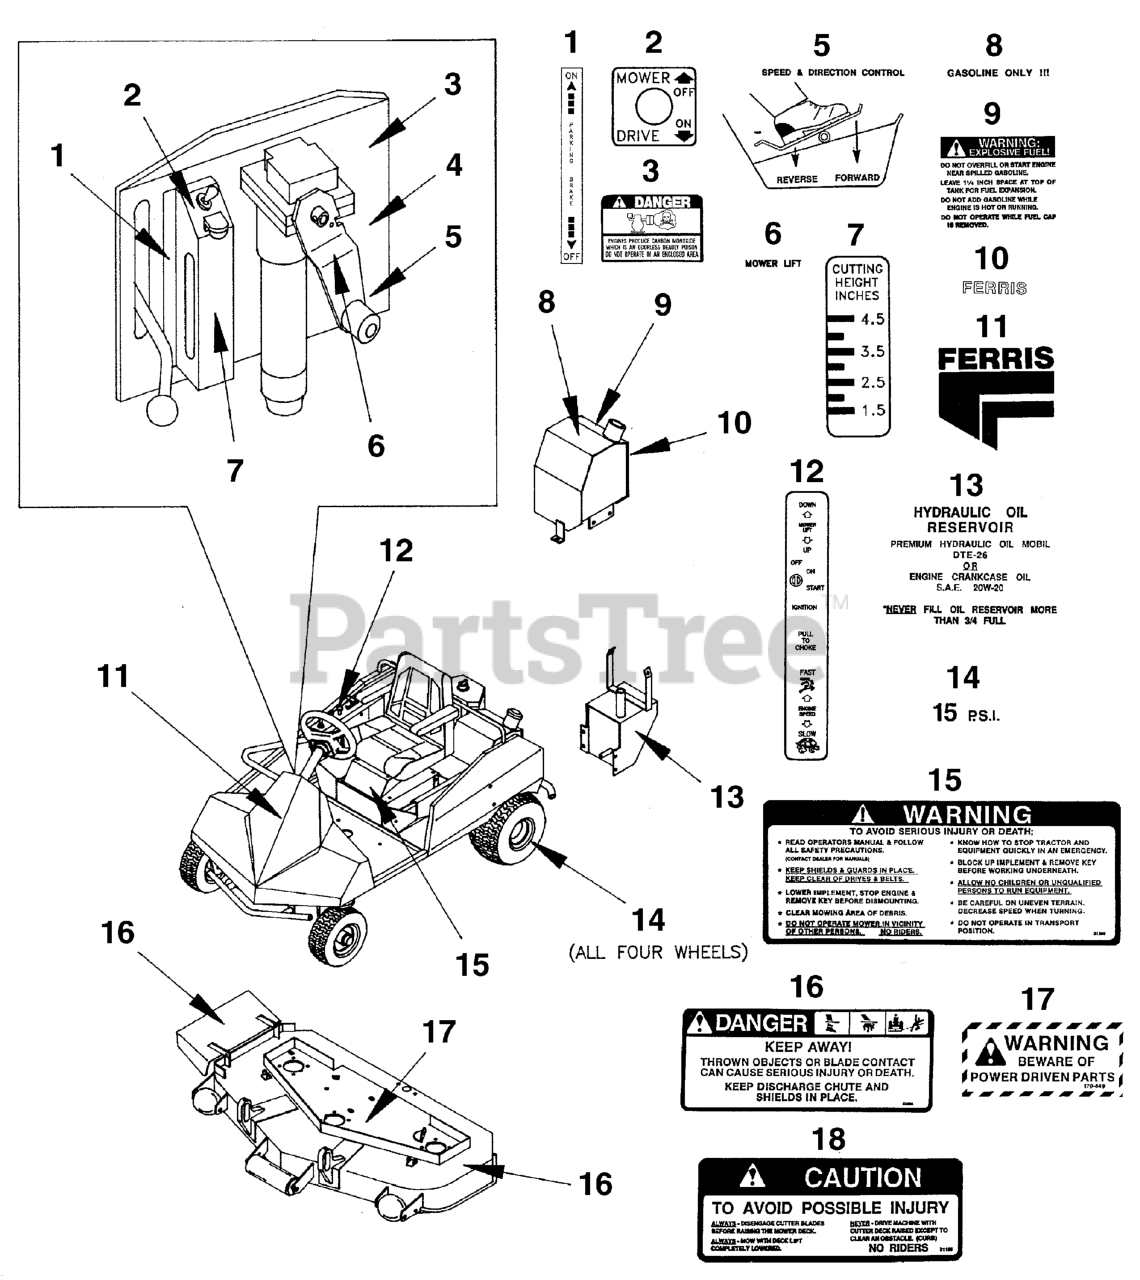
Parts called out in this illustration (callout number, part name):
1	DECAL, Parking Brake
2	DECAL, Drive Mower
3	DECAL, Danger, Carbon Monoxide
4	DECAL, Serial Tag
5	DECAL, Speed Control
6	DECAL, Mower Lift
7	DECAL, Height of Cut
8	DECAL, Gasoline Only
9	DECAL, EXPLOSIVE FUEL
10	DECAL, FERRIS TEXT & LOGO
11	DECAL, Ferris Logo, 10-3/4"
12	DECAL, Ignition
13	DECAL, Reservoir Hydraulic Oil
14	DECAL, 15 P.S.I.
15	DECAL, WARNING Operation
16	DECAL, DANGER DO NOT OPERATE W/O DEFLECT
17	DECAL, Warning
